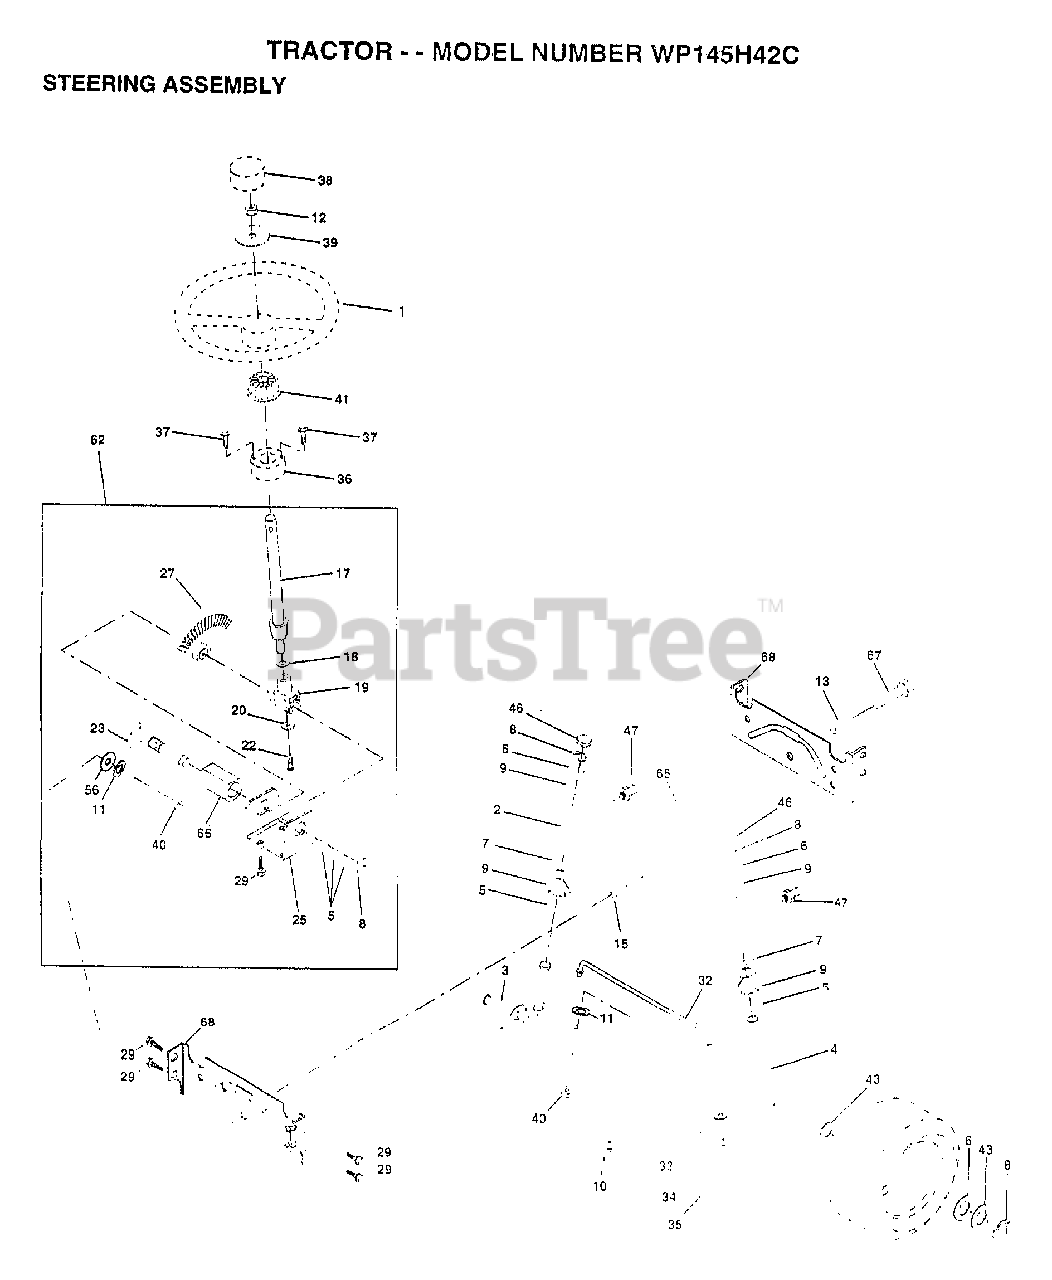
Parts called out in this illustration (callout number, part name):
2	AXLE ASM
3	SPINDLE.ASM.LH
4	"SPINDLE ASM,RH"
5	WASHER .T
6	WASHER
7	WASHER
8	RING
9	COL. SRTG. BEAR.
10	DRAGLINK-STAMPED
11	LOCKWASHER
13	BEARING AXLE
15	"NUT-LOC,FLANGE LT"
17	SHAFT ASM STEERNG
18	THRUST WASHER
19	SUPPORT.SHAFT
22	SCREW HEX SOC1/4-
25	BRKT-STEERING
27	GEAR SECTOR
29	SCREW
32	ROD.TIE.19.75
33	WASHER M
34	LOCKWASHER
35	NUT.LOCK.5/16-24
36	BUSHING.STRG.3/4
37	"SCREW-TT,10-32 FL"
38	"INSERT,STR WHEEL"
39	WASHER
40	GRIPCO NUT
41	ADAPTER LT
43	WASHER
46	CAP
47	ZERK M
62	KIT STEERING ASM
65	SPACER AXLE
66	"BEARING-ARM,PITMA"
67	BOLT
68	BRACE AXLE
